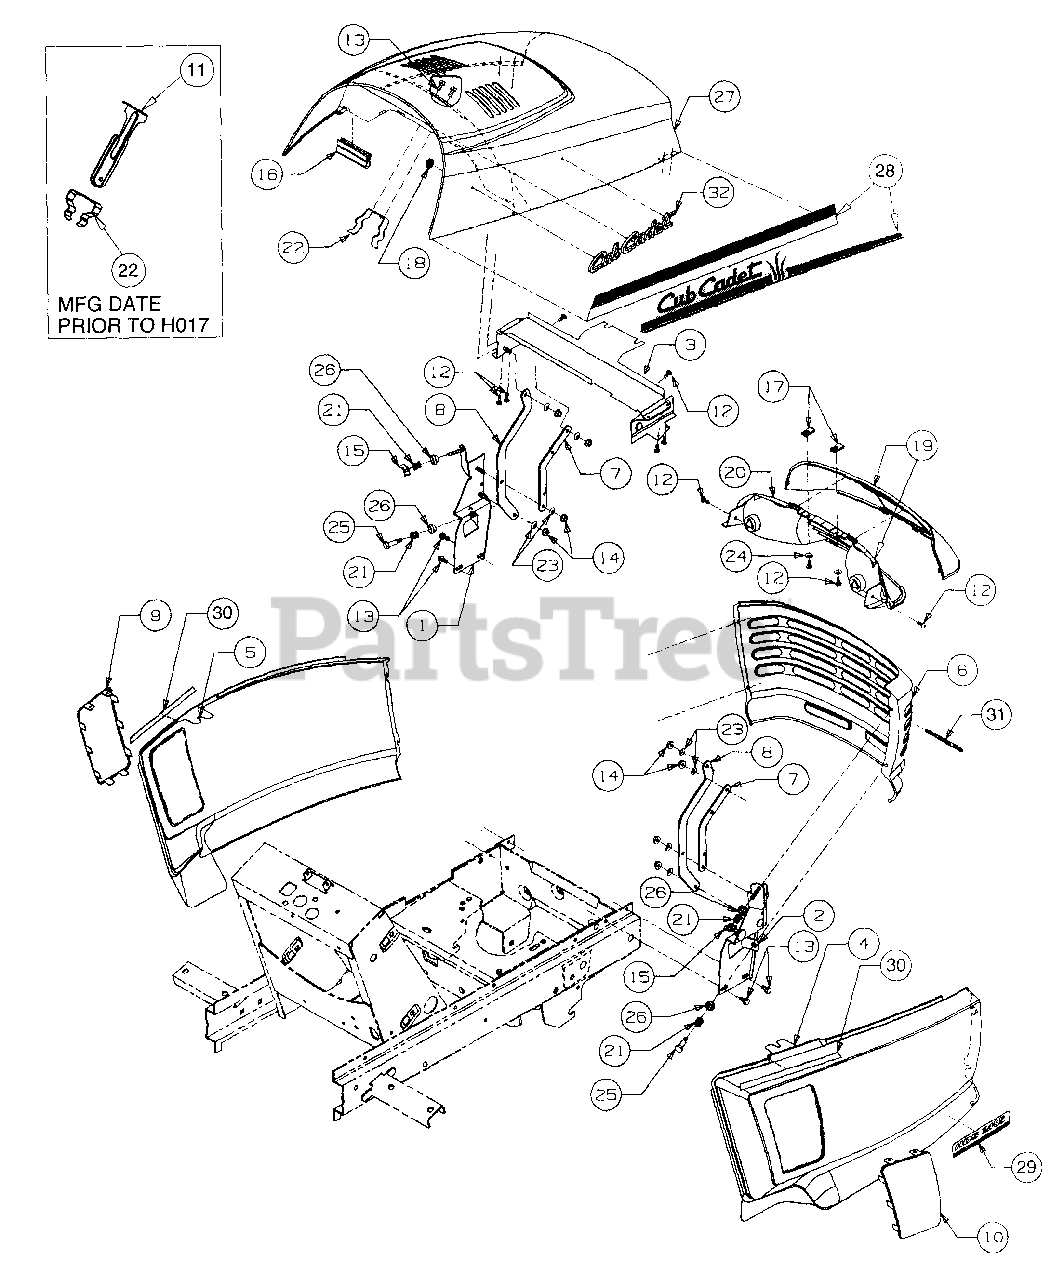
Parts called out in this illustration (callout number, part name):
1	Bracket, Grille LH
2	Bracket, Grille RH
3	Bracket, Upper Hood
4	Panel, RH Side
5	Panel, LH Side
8	Link, Long Hood
9	Screen, LH Panel
10	Screen, RH Panel
11	Guide, Hood
12	Screw, Truss Mach Tapp, #10 x .50
13	Screw, Hex Wash Hd Tapp, 1/4 x .50
14	Nut, Hex Flange Lock, 1/4-20
15	Nut, Wing, 1/4-20
16	Seal, Heat Baffle
17	Nut, U-Type Speed, #10
18	Retainer, Push Nut
19	Headlight Assembly
20	Reflector, Headlight
21	Spring, Compression, .50 OD x .50 Lg
22	Spring, Hood Latch
23	Washer, Spring, .265 x .562 x .025
24	Washer, Flat, .218 x .62 x .063
25	Bolt, Shoulder, .31 Dia x .75 Lg
26	Bushing, Tapered
27	Hood, Series 2000
28	Graphic, Hood, RH
29	Graphic, HDS 2165
30	Strip, Protective
31	Graphic, Warning HOT
32	Script w/Studs, Cub Cadet
